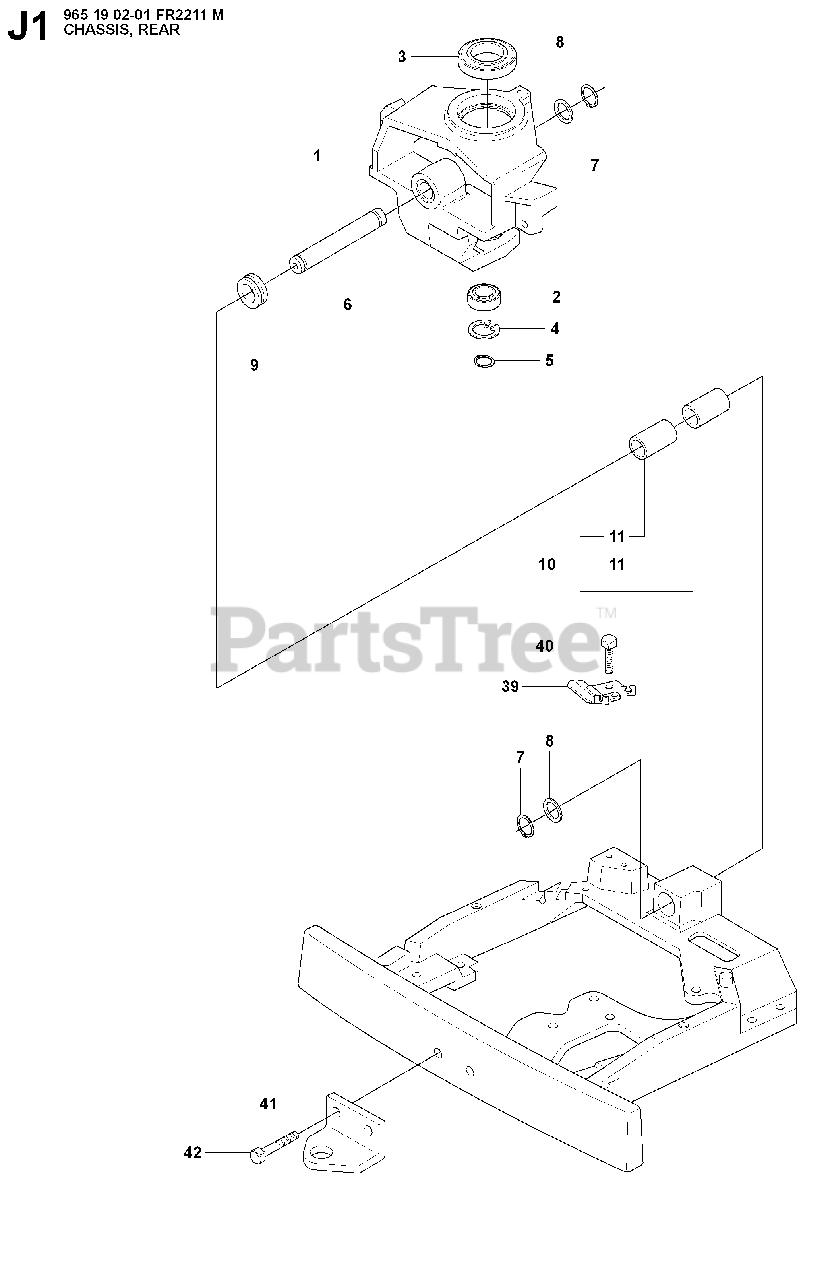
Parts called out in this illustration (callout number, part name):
2	BALL BEARING 6005-2RS
3	BALL BEARING 6010 2RS1
4	CIRCLIP SGH 47
5	RETAINING RING SGA 25
7	RETAINING RING SGA 25
41	DRAW RING
42	SCREW M10X25
